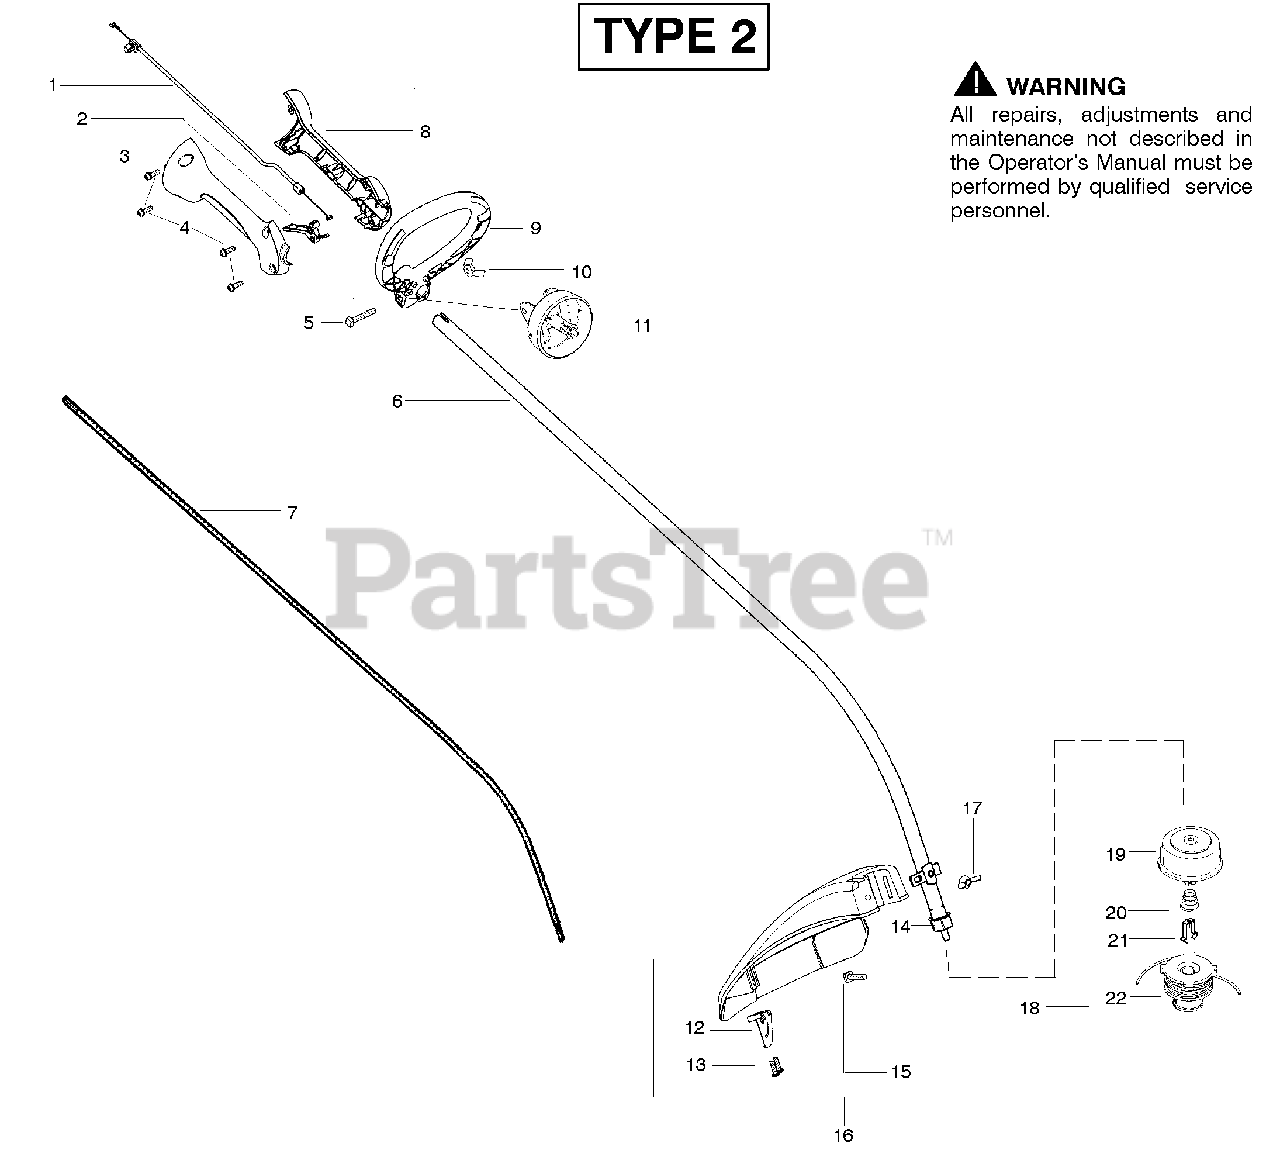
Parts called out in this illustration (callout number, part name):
1	Assy-Throttle Cable
3	Throttle Hsg. (Right)
4	Screw-Throttle Hsg.
6	Kit-Drive Shaft Assy.
8	Throttle Hsg. (Left)
9	Assy-Handle
10	Wingnut
11	Spool Buddy
13	Screw-Line Limiter
16	Kit-Shield Assy
17	Wingnut
18	Accy-TNG VI Cutting Head
19	Assy-Hub
20	Spring-Compression
21	Clip-Retainer-Head
22	Accy- Spool w/Line
